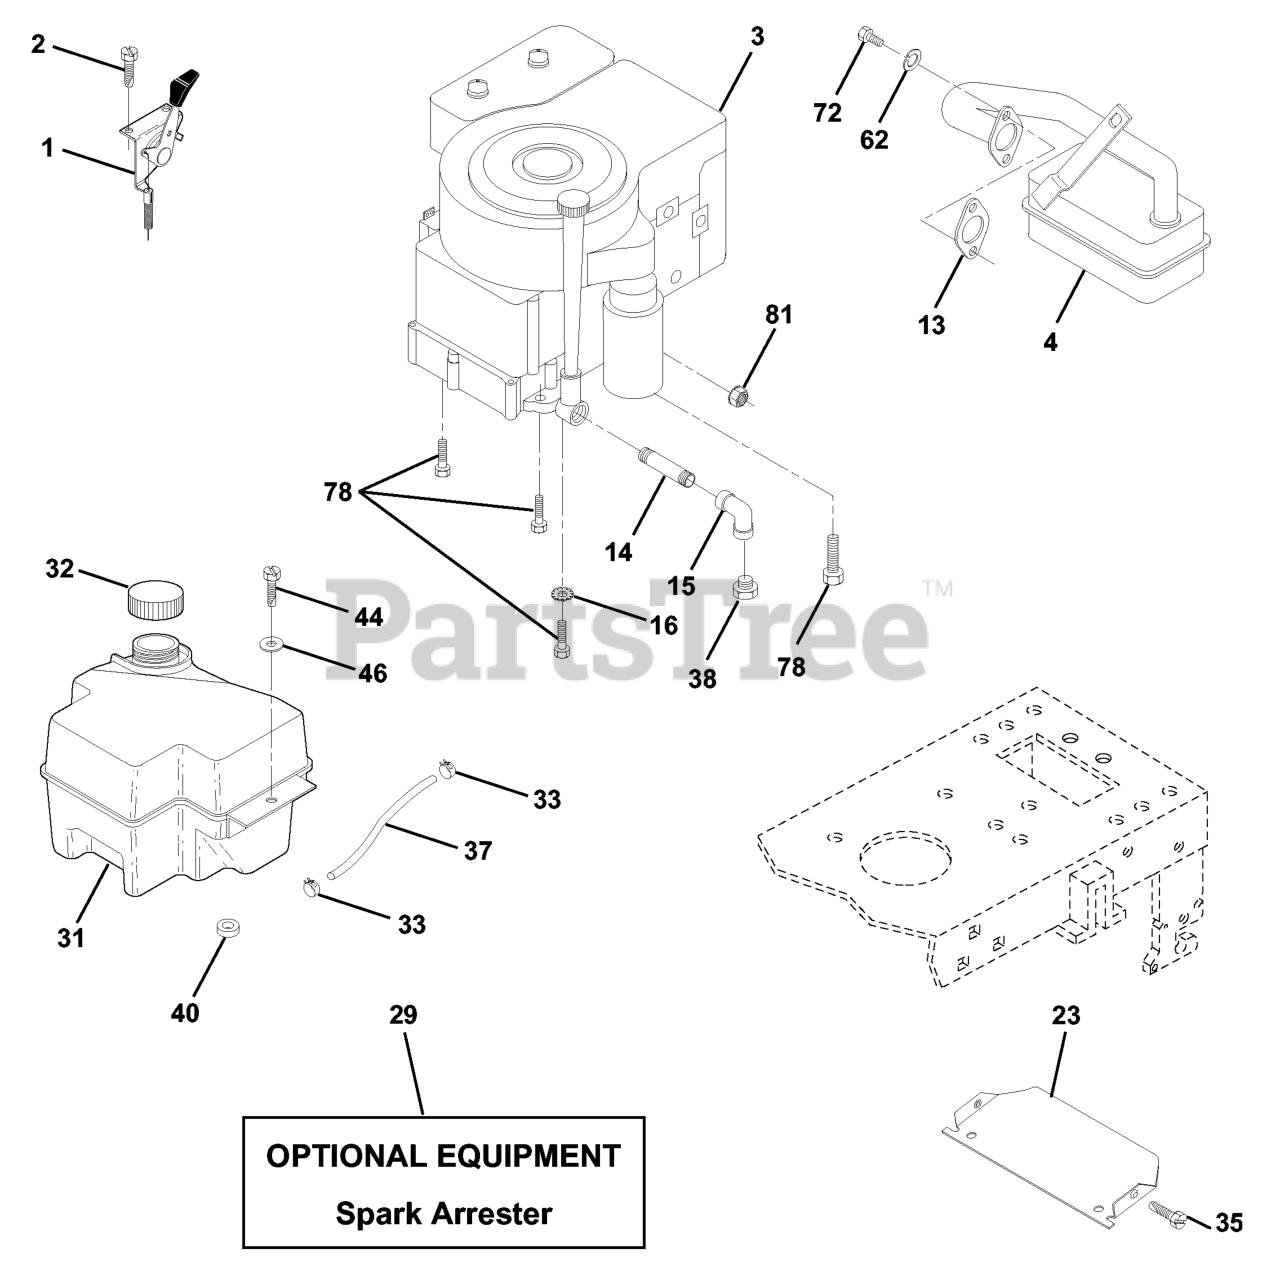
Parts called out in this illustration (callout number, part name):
1	CHOKE CONTROL
2	SCREW LT
4	MUFFLER.SINGLE.B&S.10-12HP
13	GASKET.ENG.1.313 ID.TIN PLATED
14	Nipple Pipe 3/8 Npt X 3"
15	ELBOW
16	LOCKWASHER
23	SHIELD HEAT
29	KIT.SPARK ARRESTOR 794945 B&S
31	FUEL TANK
32	FUEL CAP
33	HOSE CLAMP
35	SCREW.THDROL.5/16-18X3/4.TTY
37	LINE.FUEL.20
38	Plug Oil Drain
40	BUSHING.SNAP.NYL.BLK.
44	SCREW HEX CRT
46	WASHER
62	WASHER.LOCK.HVY.HLCL.SPR.5/16
72	SCREW
78	SCREW
81	NUT FLANGE 1/4-20 STARTER NUT
